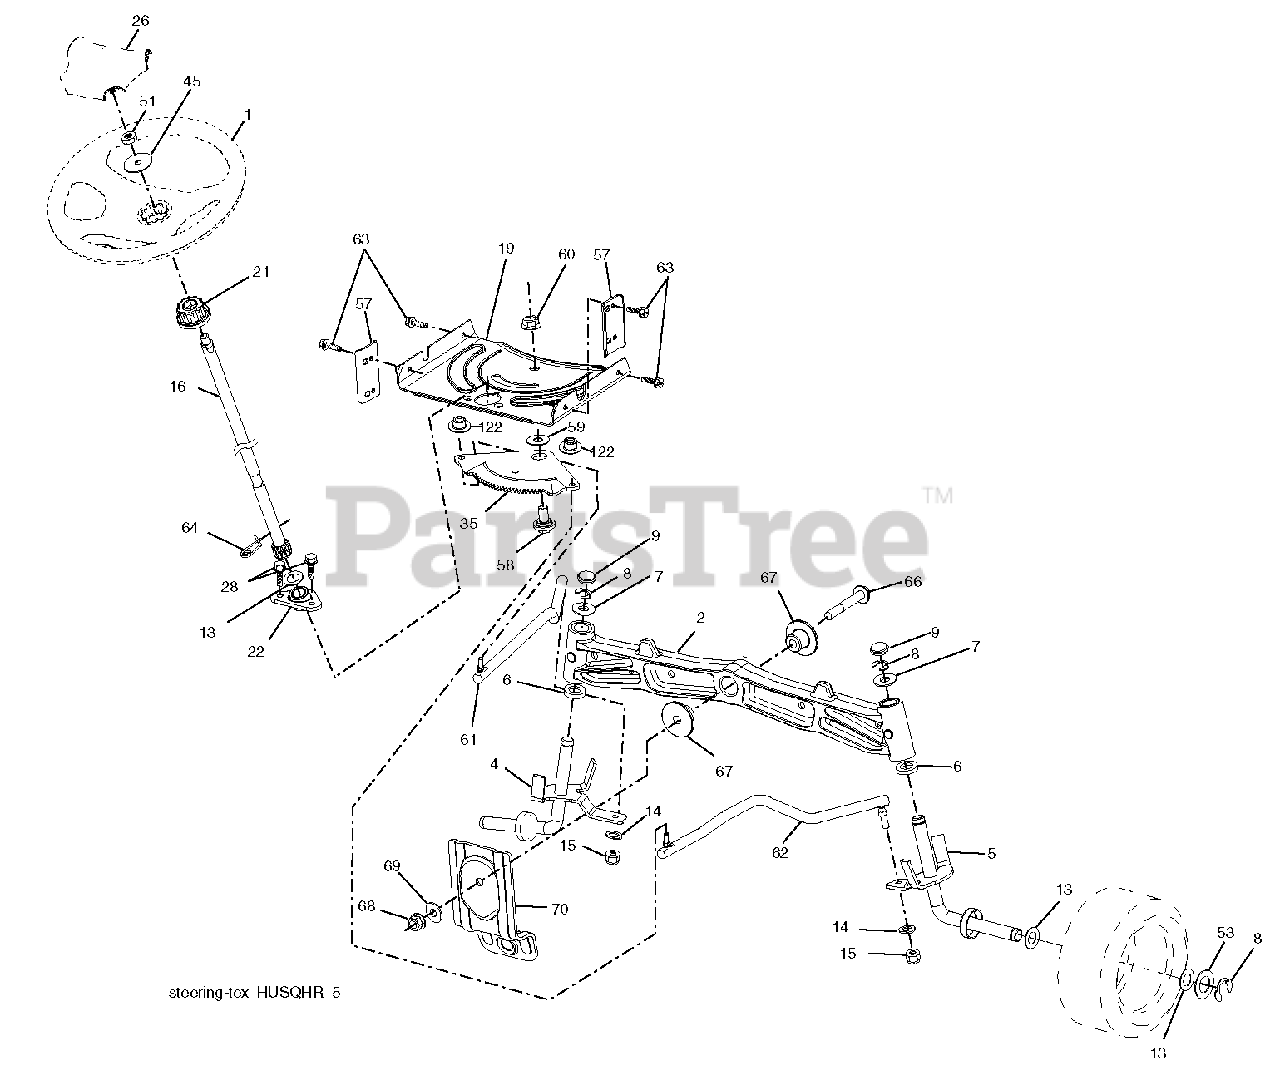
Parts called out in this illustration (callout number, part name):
1	RP WHEEL.STEER.HUSQ.PREM.OVMLD
2	AXLE.CAST.IRON
4	SPINDLE.WELDED.LH.15"TEX
5	SPINDLE.WELDED.RH.15"T
6	THRUST WASHER
9	CAP.SPINDLE.BLACK
14	WASHER, LOCK 3/8
15	NUT CROWNLOCK 3/8-24
16	SHAFT, STEERING
19	PLATE.STEER.DDL.NLT/NG
21	ADAPTER, WHEEL STNG..
22	STEERING.SUPT.LOWER.
26	RP INSERT.CAP.WHL.STRG.HUSQ.
28	SCREW, 3/8-16X3/4
35	GEAR.SECTOR.PLATE.DDL.
45	WASHER 9/16"ID, 2 3/8"OD
51	NUT.HEX.1/2-20
53	WASHER.HARDENED
57	BRKT.UPSTOP.GT/LT.TEX
58	BOLT.SHOULDER.SECTOR.P
59	WASHER.THURST.SECTOR.S
60	NUT FLANGE LOCK 5/8-11
61	DRAGLINK.LH.BALLSTUD.D
62	DRAGLINK.RH.BALLSTUD.D
63	SCREW
64	RETAINER.CLIP.SPRING.S
66	BOLT HEX FGHD 7/16-14 X 3 SERR
67	BUSHING.PM.FRONT AXLE
68	NUT.LOCK.FLANGE.7/16
69	WASHER.1.5X.505X.118
70	BRKT.DECK.SUSPENSION.F
122	CAP.GEAR.SECTOR.TEX
